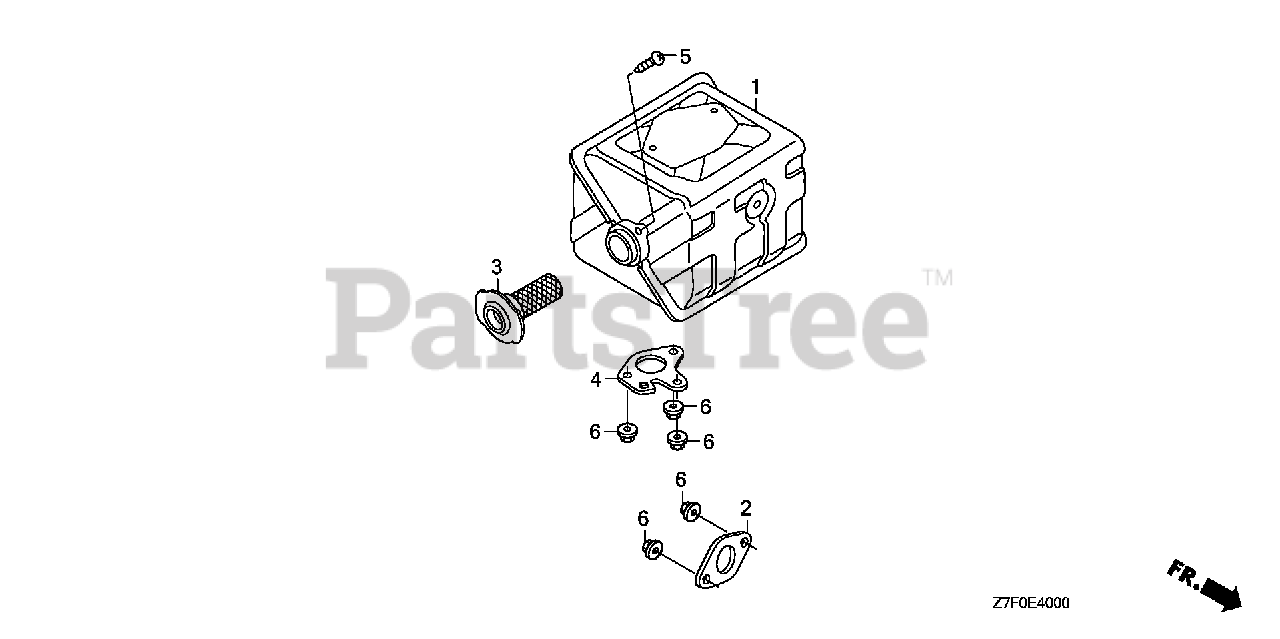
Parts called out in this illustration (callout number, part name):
1	MUFFLER (100DB)
2	GASKET, EX. PIPE
3	ARRESTER, SPARK
4	GASKET, MUFFLER (ARRESTER) (NIPPON LEAKLESS)
5	SCREW, TAPPING (5X8)
5	SCREW, TAPPING (4X6)
6	NUT, FLANGE (8MM)
